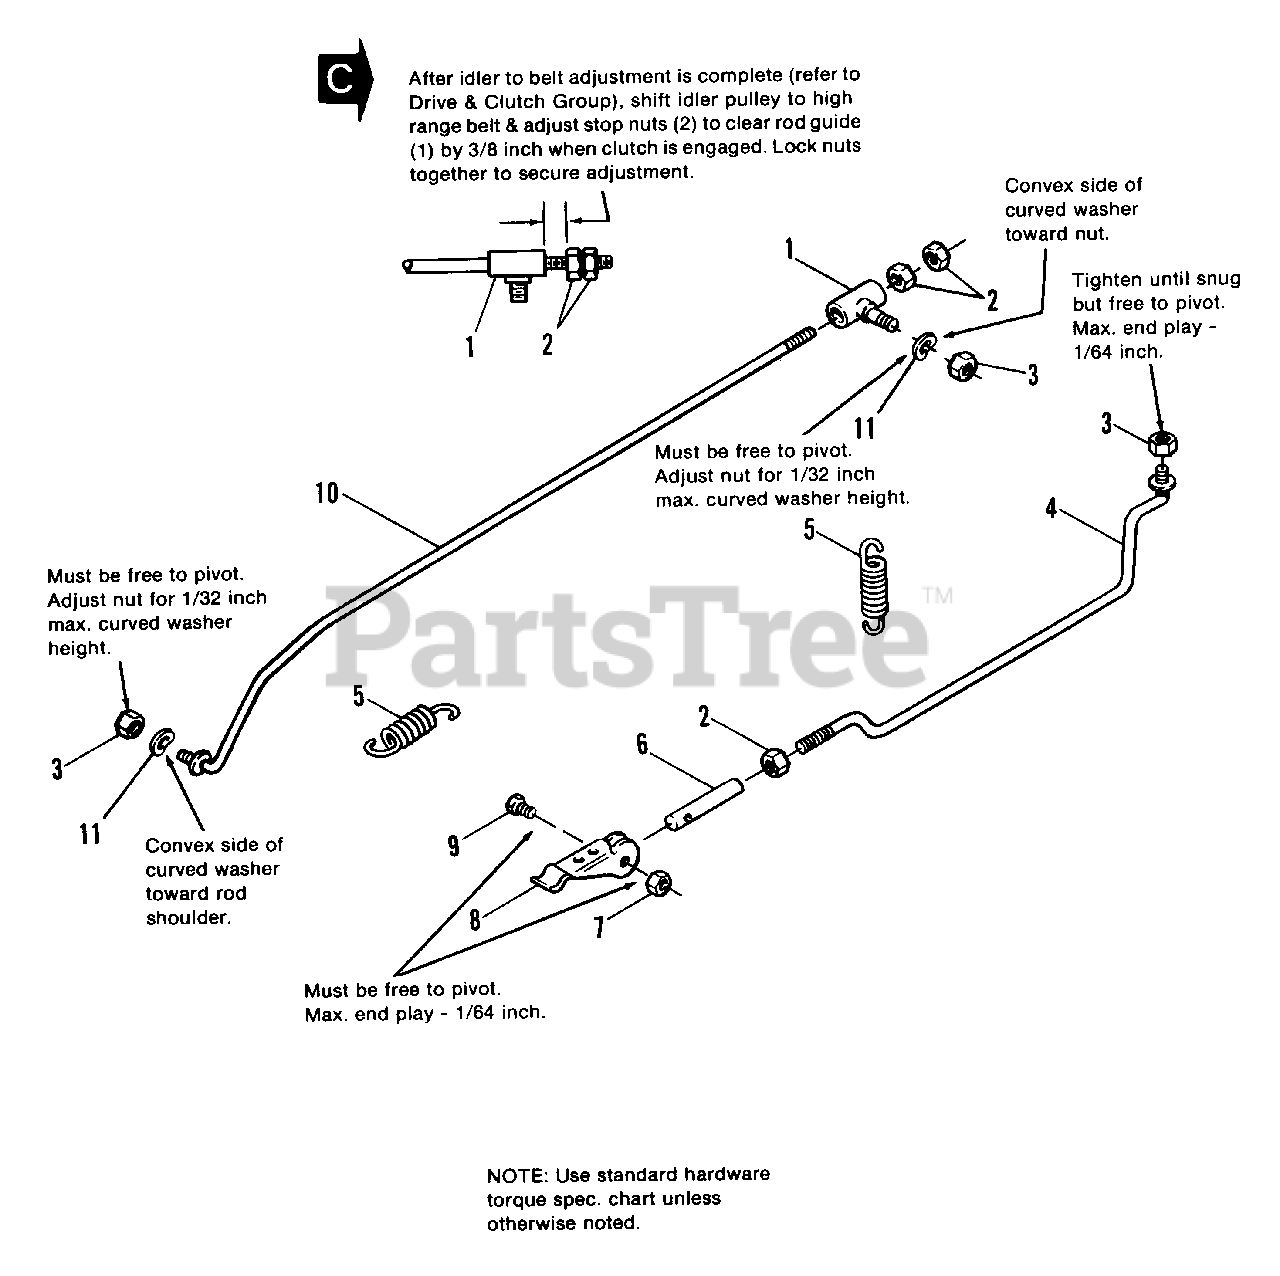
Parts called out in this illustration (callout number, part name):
1	GUIDE ASSY., Rod
2	NUT, Hex, Full, 5/16-18
3	LOCKNUT, Hex, 5/16-18
4	ROD ASSY., Parking Brake
7	LOCKNUT, Hex, 1/4-20
8	LEVER, Parking Brake
9	CAPSCREW, Hex Hd., 1/4-20 x 1
10	ROD ASSY., Clutch & Brake
11	WASHER, Curved Spring
